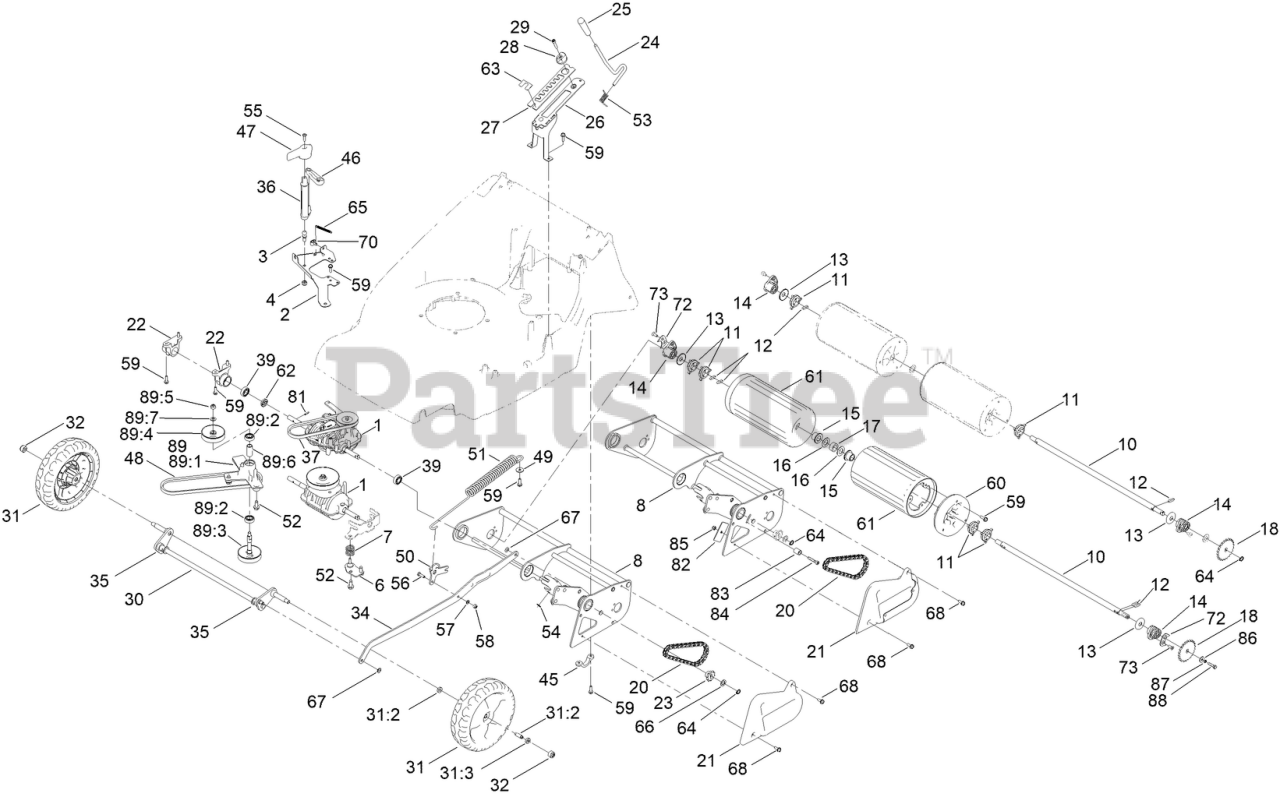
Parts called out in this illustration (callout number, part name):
1	MG510 3-SPEED GEARBOX
2	GEARBOX MOUNTING PLATE
3	STUD-BALL
4	NUT-HEX, NI
6	GEARBOX BRACKET ASSEMBLY
7	SPRING-MOUNTING, GEARBOX
8	REAR FRAME, 56 (PRO)
10	SHAFT-ROLLER, PRO
11	CAM-DRIVE
12	KEY-DRIVE
13	WASHER-THRUST
14	BUSH, REAR ROLLER
15	BUSHING-ROLLER, OILITE
16	WASHER
17	SPACER-ROLLER
18	SPROCKET
20	CHAIN(46 PITCHES 3/8")
21	CHAIN COVER ASM
22	MOUNT-BEARING, FRAME (REAR)
23	SPROCKET, 10T
24	LEVER-HOC
25	KNOB-HOC
26	HOC TOWER ASSEMBLY
27	PLATE-HOC
28	ADJUSTER-HOC
29	SCREW-HSH
30	56 FRONT AXLE ASSEMBLY HD
31:2	BEARING-BALL
31:3	SPACER
32	NUT-HF, NI
34	CONNECTING ROD ASSEMBLY
35	BEARING-AXLE, FRONT
36	ROD-SELECTOR, 3 SPEED
37	V-BELT
39	BEARING, BALL 12MM
45	AXLE- SUPPORT, REAR
46	ARM-SELECTOR, 3 SPEED
47	KNOB- SELECTOR, 3 SPEED
48	V-BELT
49	WASHER
50	SPRING LOAD LEVER
51	SPRING COUNTER BALANCE
52	SCREW-HWH
53	SPRING-TORSION, HOC
54	GRIP-FIX
55	SCREW
56	SCREW-HH
57	WASHER-PLAIN
58	NUT-NYLOC
59	SCREW-TAPTITE
60	CAP-ROLLER, END
61	ROLLER SHELL ASSEMBLY
62	RETAINING COLLAR, DRIVE SHAFT
63	DECAL-HOC
64	CIRCLIP-EXTERNAL, HD
65	LEVER-SPRING, CLUTCH (RETURN)
66	WASHER-THRUST
67	WASHER-STARLOCK
68	SCREW-TAPTITE
70	CLIP-CONDUIT, TWIN
72	BEARING SUPPORT PLATE
73	SCREW-TAPTITE
81	PIN, ROLL, 3MM X 16MM
82	BACK PLATE, TENSIONER
83	PULLEY, TENSIONER
85	NUT-NYLOC
86	WASHER-PLAIN
87	WASHER-SPRING
88	BOLT-HH
89	JACK SHAFT ASSEMBLY
89:1	JACK SHAFT BRACKET
89:2	BEARING, BALL 12MM
89:3	WELDED JACK SHAFT ASM
89:4	SPLIT PULLEY UPPER
89:5	NUT-HEX, NI
89:6	SPACER TUBE, BEARING
89:7	WASHER-PLAIN
